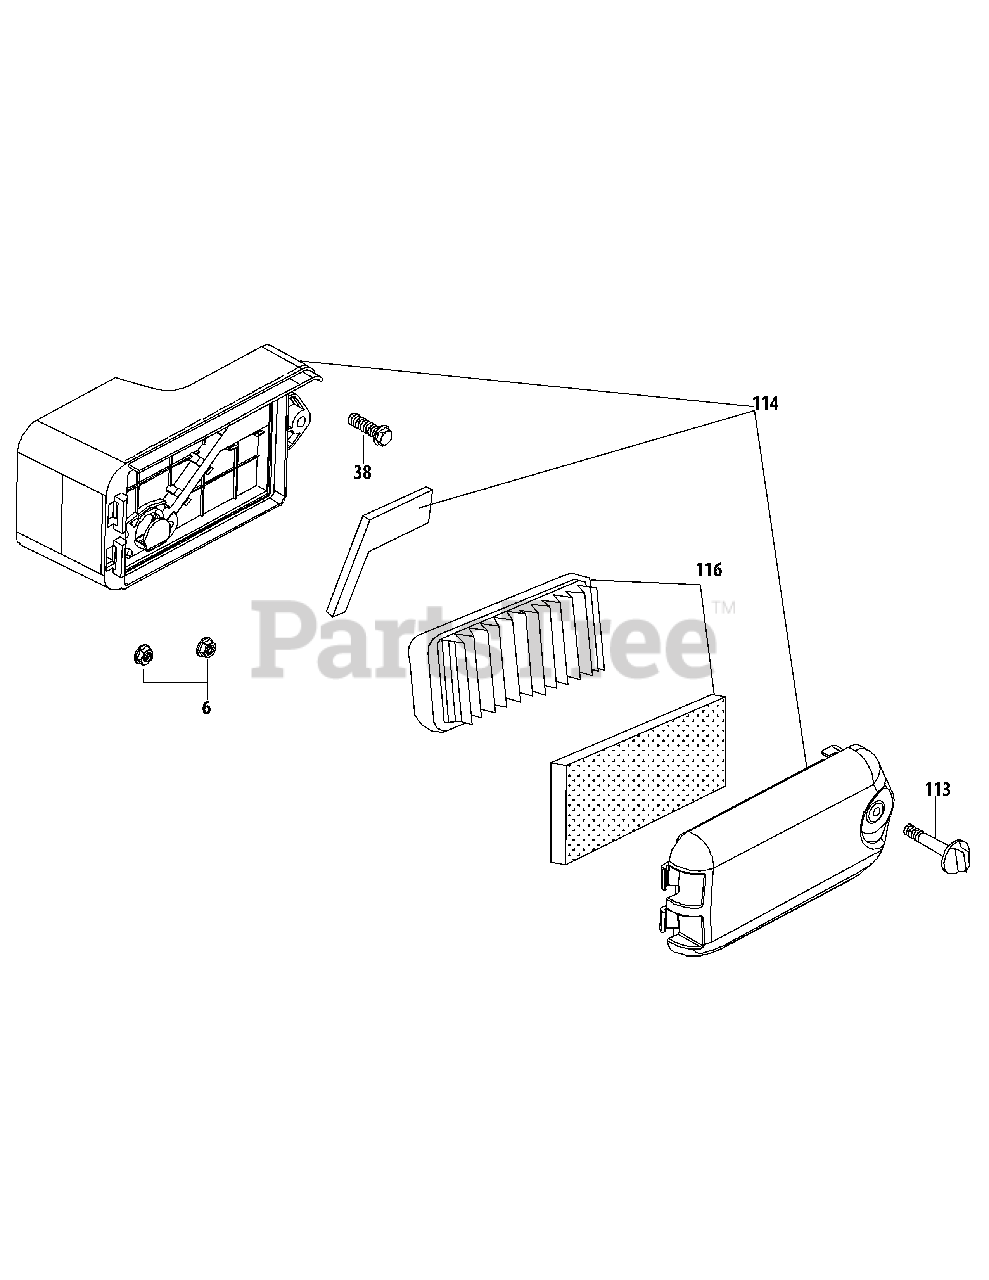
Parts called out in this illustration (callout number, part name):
6	Nut M6 X 10 Mm
38	Bolt M6X35
113	Air Filter Cover Thumb Screw
114	Air Filter Cover Asm
116	Air Cleaner Kit
